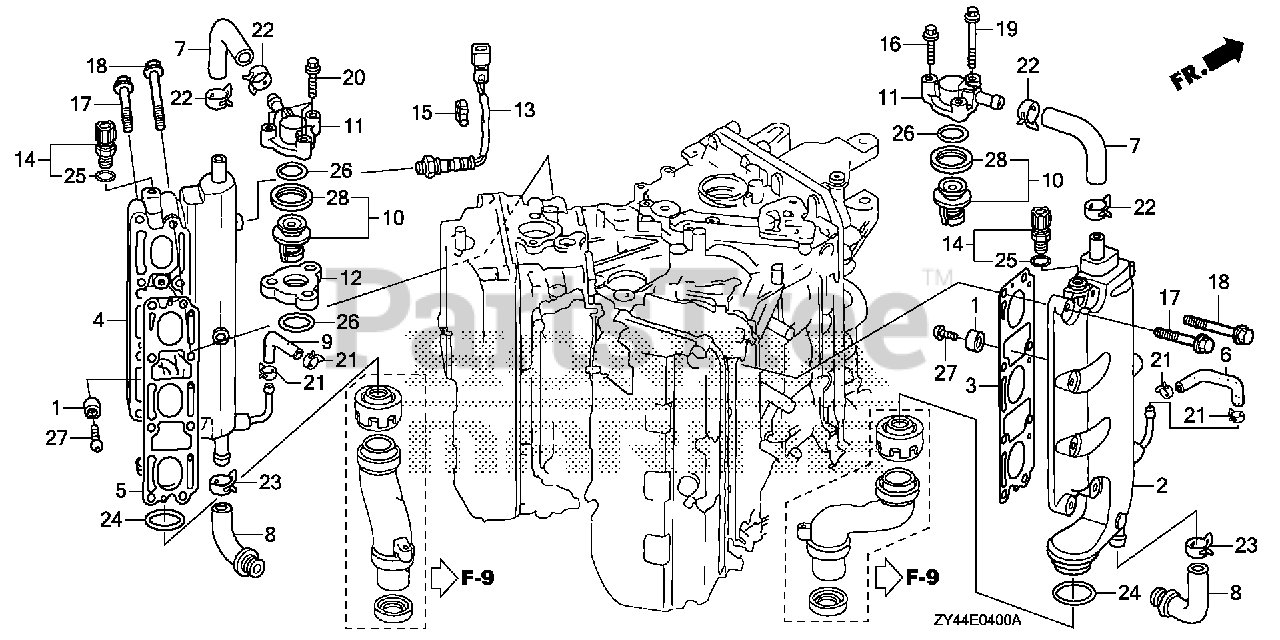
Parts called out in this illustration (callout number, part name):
1	METAL, ANODE
2	MANIFOLD, R. EX. *NH8* (DARK GRAY)
3	GASKET, R. EX. MANIFOLD
4	MANIFOLD, L. EX. *NH8* (DARK GRAY)
5	GASKET, L. EX. MANIFOLD
6	TUBE, R. WATER RETURN
7	TUBE, WATER RELIEF
8	TUBE, WATER
9	TUBE, L. WATER RETURN
10	THERMOSTAT ASSY.
11	COVER, THERMOSTAT *NH8* (DARK GRAY)
12	SPACER, THERMOSTAT *NH8* (DARK GRAY)
13	SENSOR, OXYGEN
14	SENSOR ASSY., WATER TEMPERATURE
15	CLIP, BRAKE PIPE (A)
16	BOLT, FLANGE (6X35)
17	BOLT, FLANGE (8X40)
18	BOLT, FLANGE (8X60)
19	BOLT, FLANGE (6X60)
20	BOLT, FLANGE (6X50)
21	CLAMP, TUBE (D10.5)
22	CLAMP, TUBE (D29)
23	CLAMP, TUBE (D21)
24	O-RING (66.4X3.1)
25	O-RING (9.5X1.9)
26	O-RING (31.5X2.4) (ARAI)
27	SCREW, PAN (6X18)
28	RUBBER, RING
